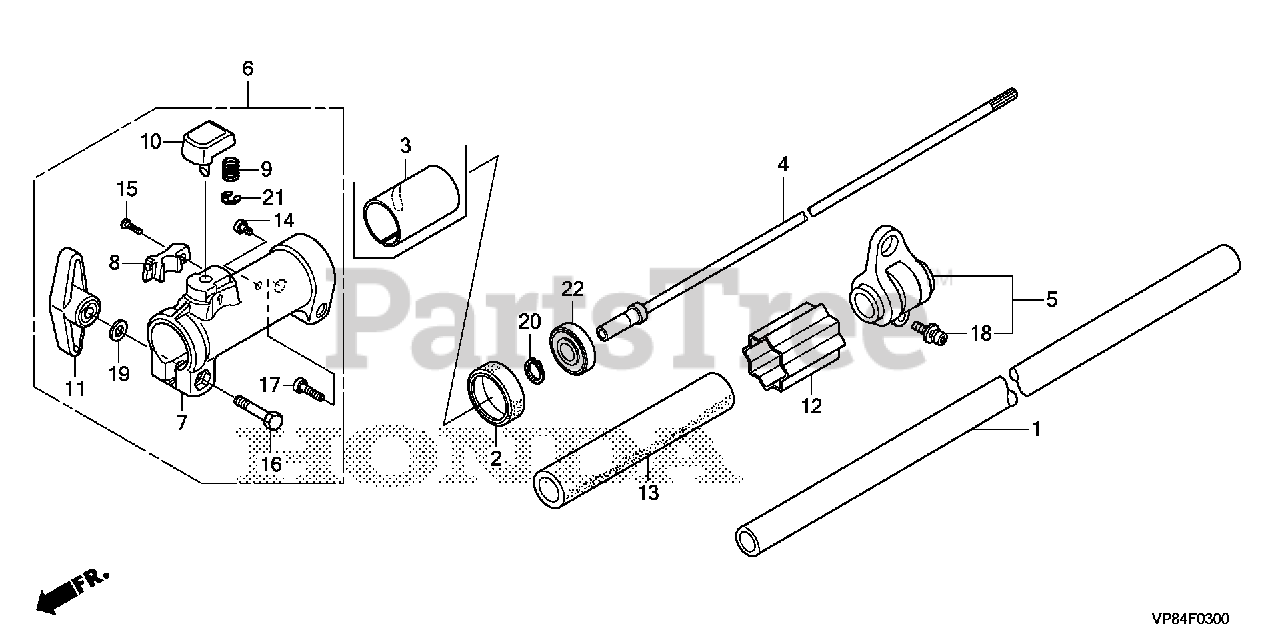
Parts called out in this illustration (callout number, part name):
1	PIPE ASSY., FRAME
2	COVER, BEARING
4	SHAFT, DRIVE
5	HANGER ASSY.
6	CASE ASSY., JOINT
7	CASE, JOINT
8	COVER, BUTTON
11	KNOB, JOINT CASE
12	COLLAR, HANDLE STOPPER
13	GRIP, HANDLE STOPPER
14	BOLT, TORX (5X10)
15	SCREW, PAN (3X10)
16	BOLT, HEX. (6X35)
17	BOLT, TORX (6X23)
18	BOLT-WASHER, TORX (5X22)
20	CIRCLIP (OUTER) (9MM)
22	BEARING, RADIAL BALL (609LL)
